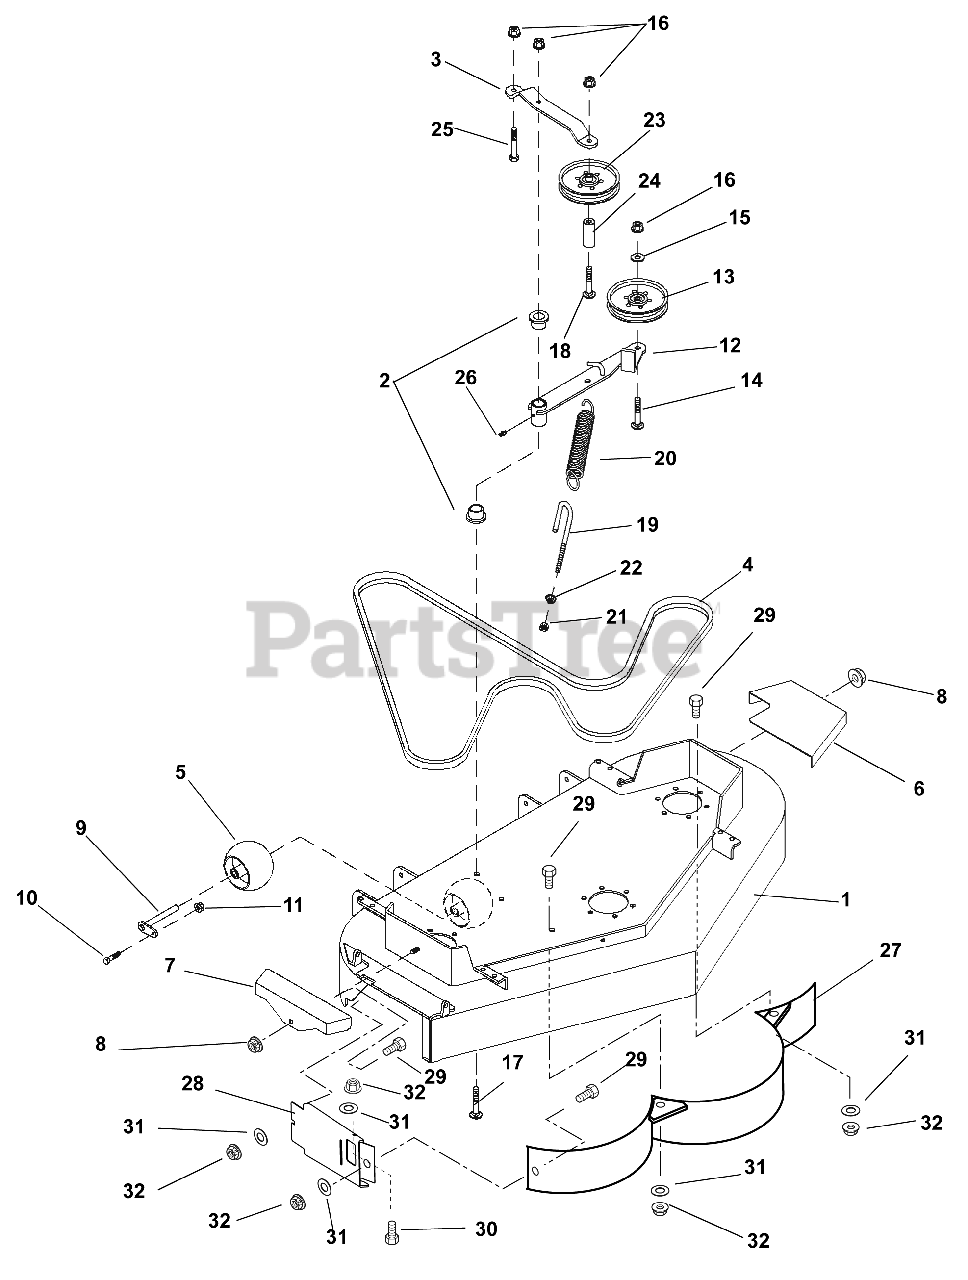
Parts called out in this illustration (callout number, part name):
1	MOWER DECK, 48" S/O
2	BUSHING
3	STRAP, IDLER PULLEY
4	BELT, ENGINE-TO-BLADES, 48"DEC
5	WHEEL, GAGE, 48" AND 52" DECK
6	COVER, LH 48/52 DECK BELT S/O
7	BELT COVER, RH 48" DECK
8	@NUT-LK-TOP-FLG .38-16 YWZC
9	PIVOT, ANTI-SCALP ROLLER
10	@BLT-RDHDSQNK .25-20X1.00 G5YZ
11	NUT-1/4" FLANGE PREVAILING TOR
12	ARM, IDLER ENGINE-TO-BLADE
13	PULLEY, FLAT TENSION IDLER
14	@BLT-RDHDSQNK .38-16X2.25 G5YZ
15	@WSHR-FL-STL.406X.812X.065 YWZ
16	@NUT-LK-CTR .38-16 YWZC
17	BOLT, 3/8-16 X 4.00 CHCS
18	BOLT, 3/8-16 X 3-3/4 CHCS
19	J-HOOK
20	SPRING, DECK BELT TENSION
21	@NUT-LK-NYL .38-16 YWZC
22	@NUT-SPNLK-FLG .375-16 YWZC
23	PULLEY, FLAT BLADE-TO-BLADE
24	SPACER, BLADE-TO-BLADE PULLEY
25	@BLT-RDHDSQNK .38-16X1.25 G5YZ
26	FITTING, LUBRICATION
27	WLDMT, 48" MULCH BAFFLE
28	PLATE, 48" MULCH BLOCKER
29	@BLT-HEX .38-16X1.00 GR5 YWZC
30	@BLT-HEX .38-16X1.25 GR5 YWZC
31	@WSHR-FL-STL.406X.812X.065 YWZ
32	@NUT-LK-NYL-FLG .38-16 YWZC
